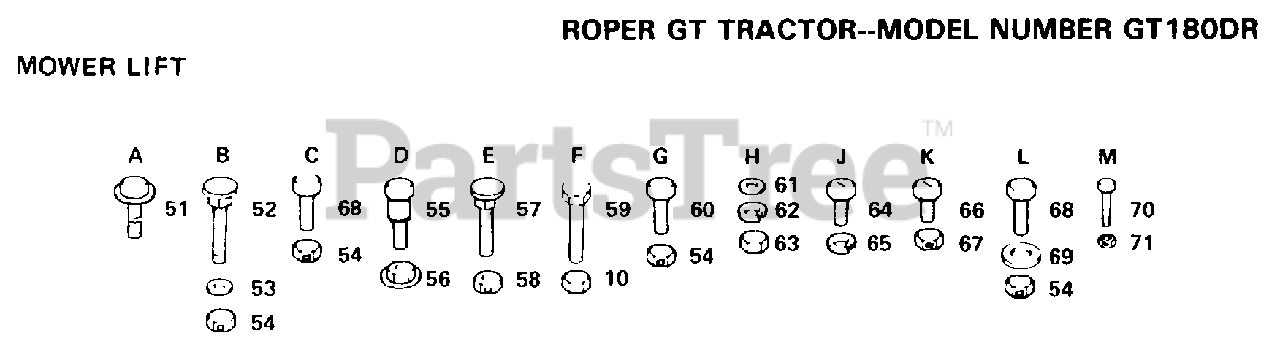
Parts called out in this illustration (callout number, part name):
51	SCREW LT
52	BOLT
53	WASHER
55	SHOULDER BOLT T
56	NUT T
57	BOLT
58	LOCKNUT
59	BOLT
61	WASHER PM
68	BOLT
69	WASHER M
70	BOLT
